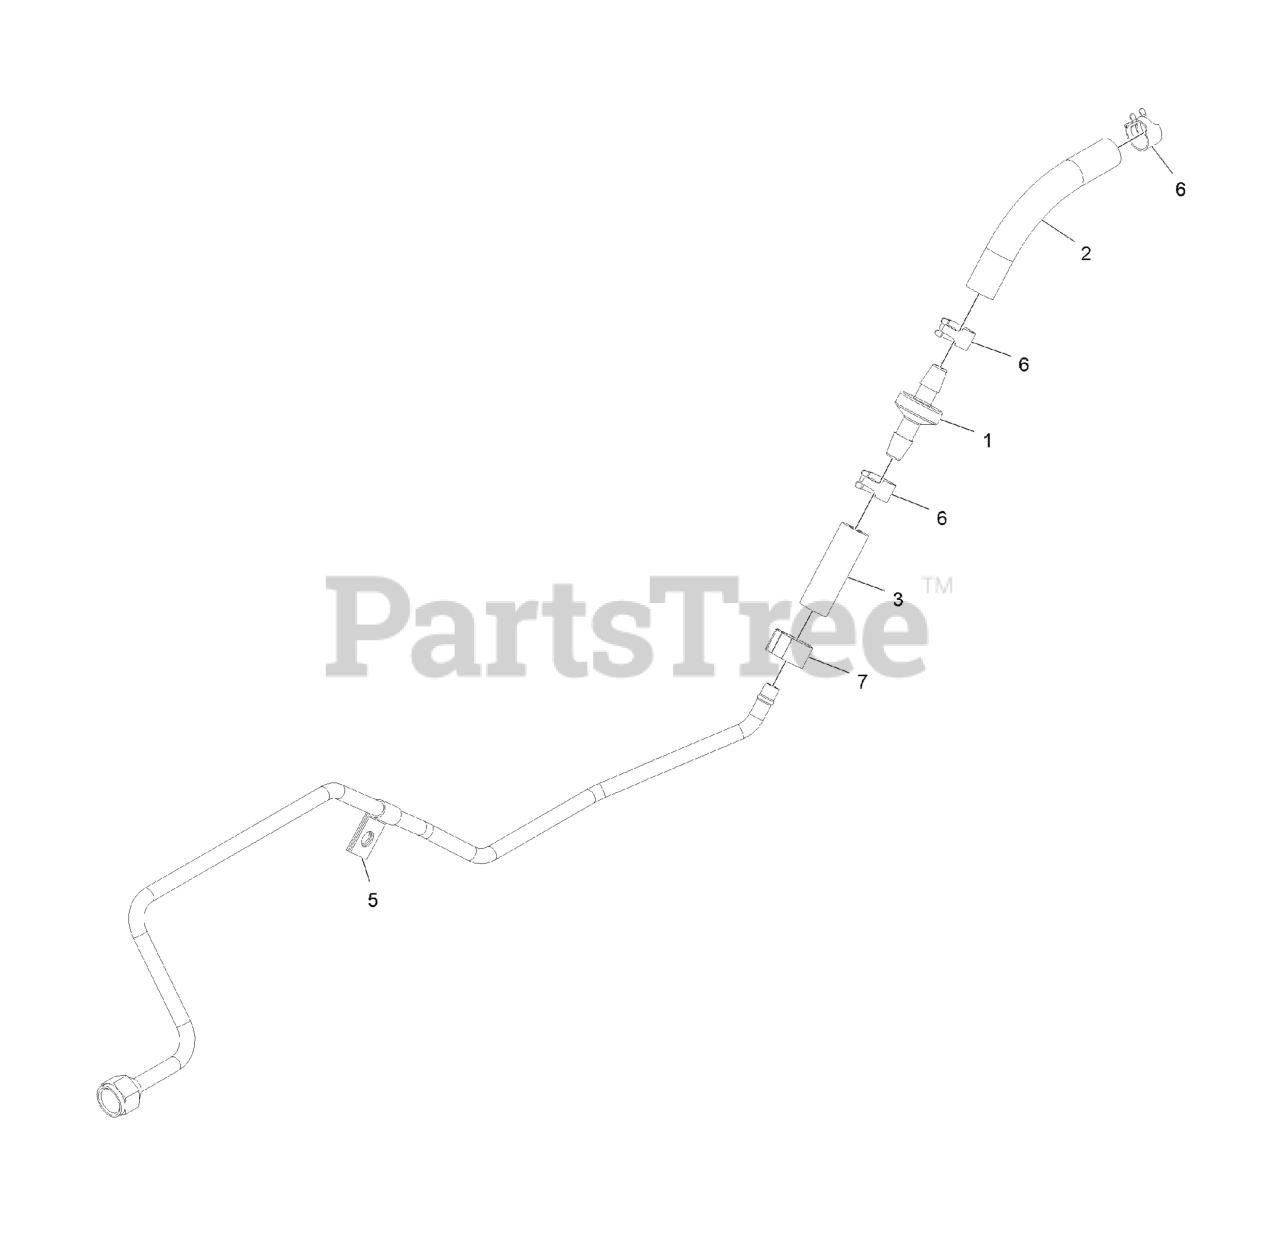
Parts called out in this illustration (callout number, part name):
1	VALVE-CHECK, FUEL
2	HOSE-FUEL
3	Hose-Fuel
5	CLIP-CLOSED, INSULATED
6	CLAMP-HOSE
7	Clamp-Hose, Fuel
